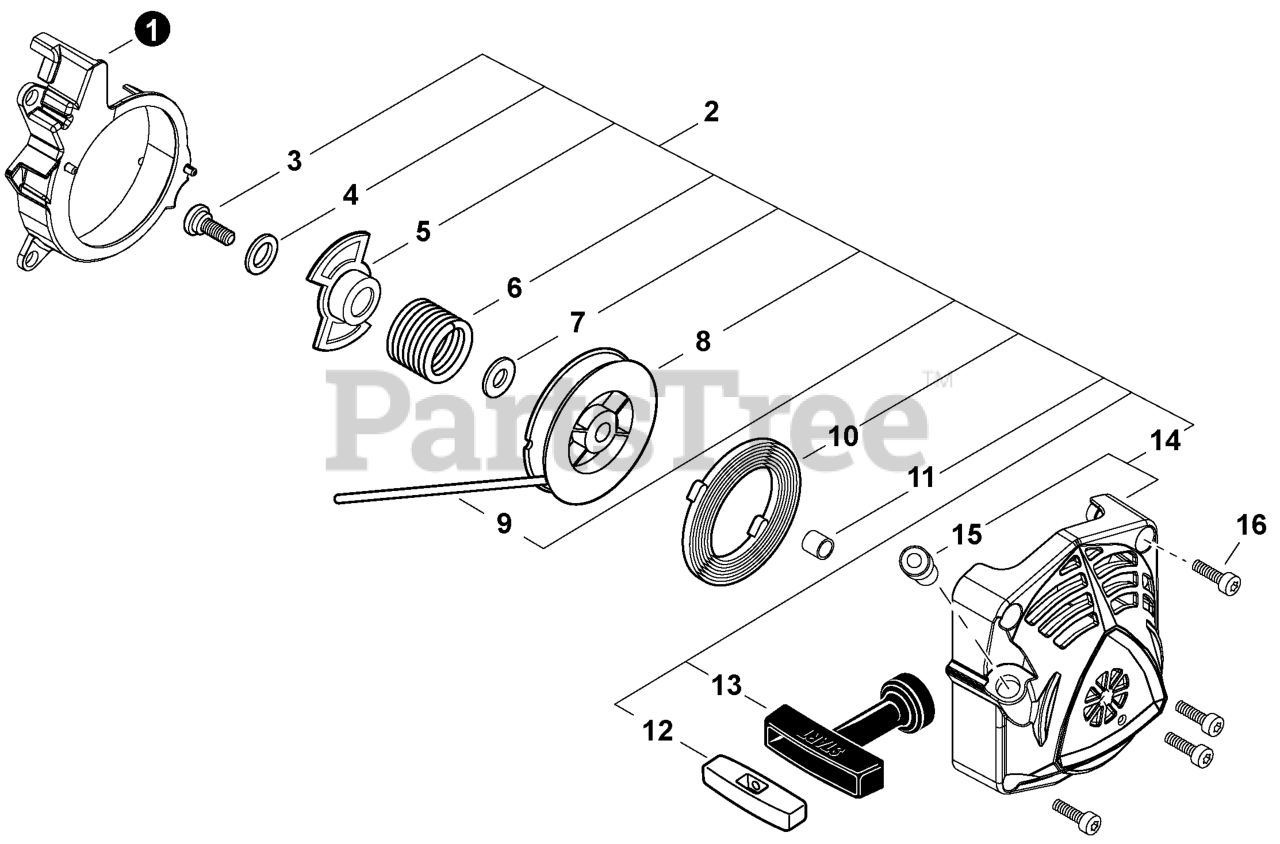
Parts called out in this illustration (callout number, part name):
1	GUARD, DEBRIS
2	STARTER ASSY, RECOIL
3	SCREW 5
4	WASHER, THRUST
5	PLATE, FRICTION
6	SPRING, FRICTION
7	WASHER 19.7
8	REEL, ROPE
9	ROPE, STARTER
10	SPRING, SPIRAL
12	RETAINER, ROPE
13	GRIP, STARTER
14	CASE, STARTER
15	GUIDE, ROPE
16	BOLT, TORX 5x20
